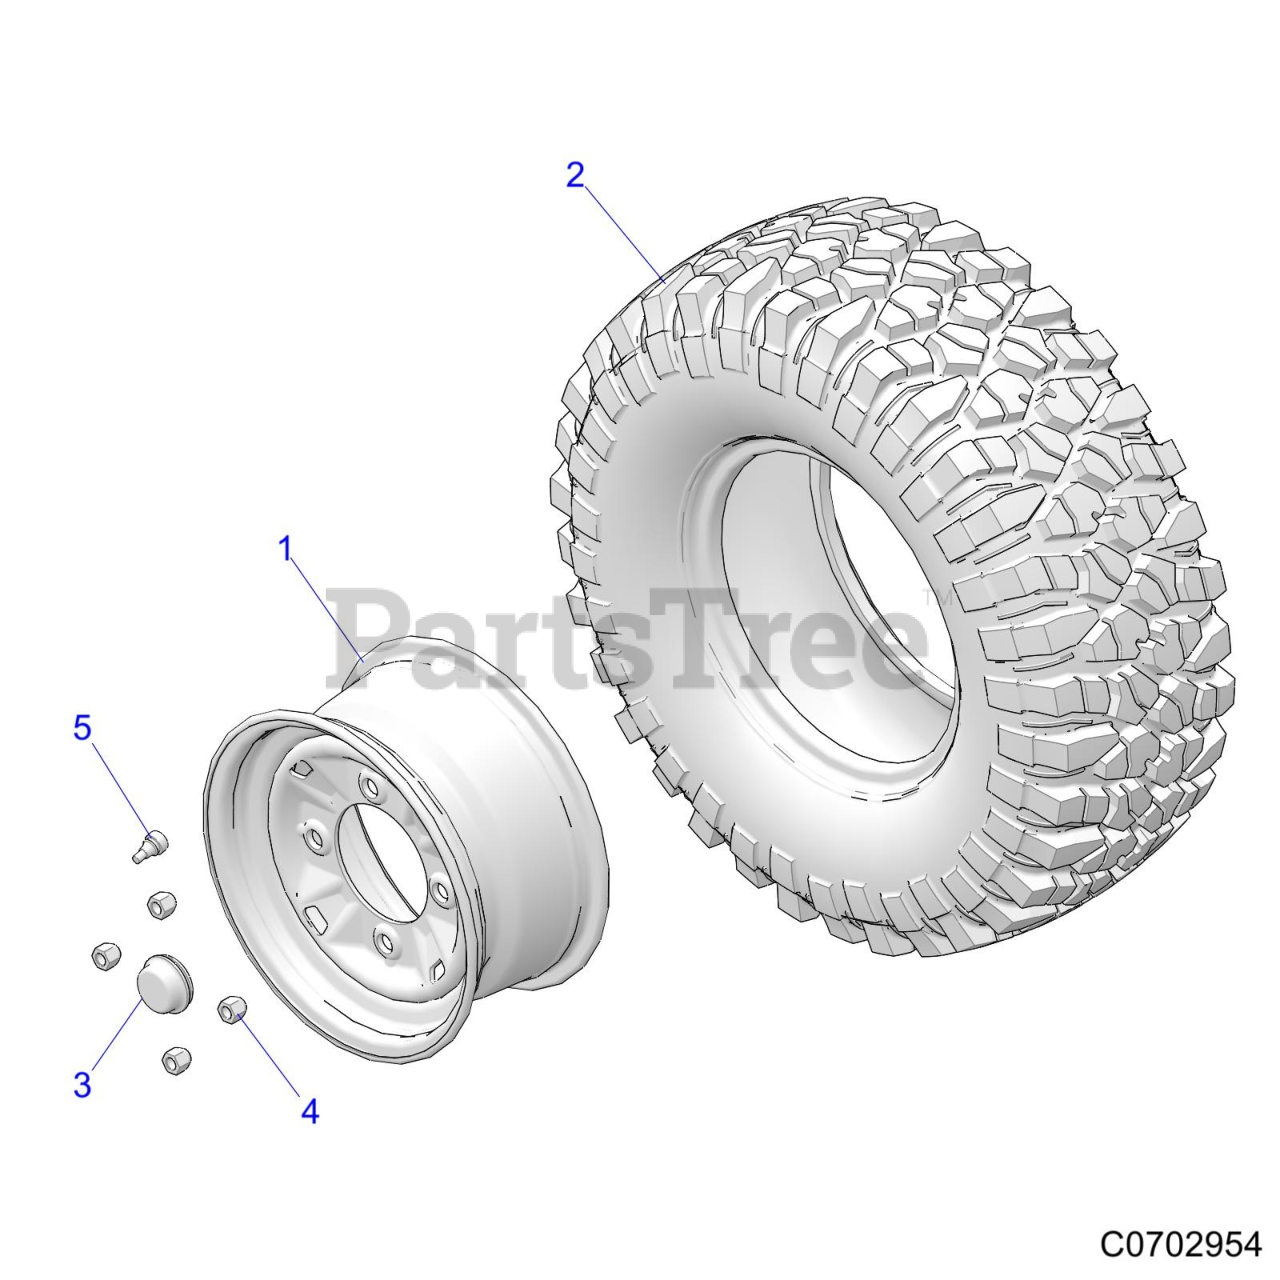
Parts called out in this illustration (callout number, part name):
1	RIM-12X6,AT,ET26.2,BLK
2	TIRE-26X10-12,8PR,DI-2042
3	HUB-DUST COVER,INTRNL LIP,BLNK
3	CAP, DUST
4	NUT-LUG,M12
5	VALVE, RIM
